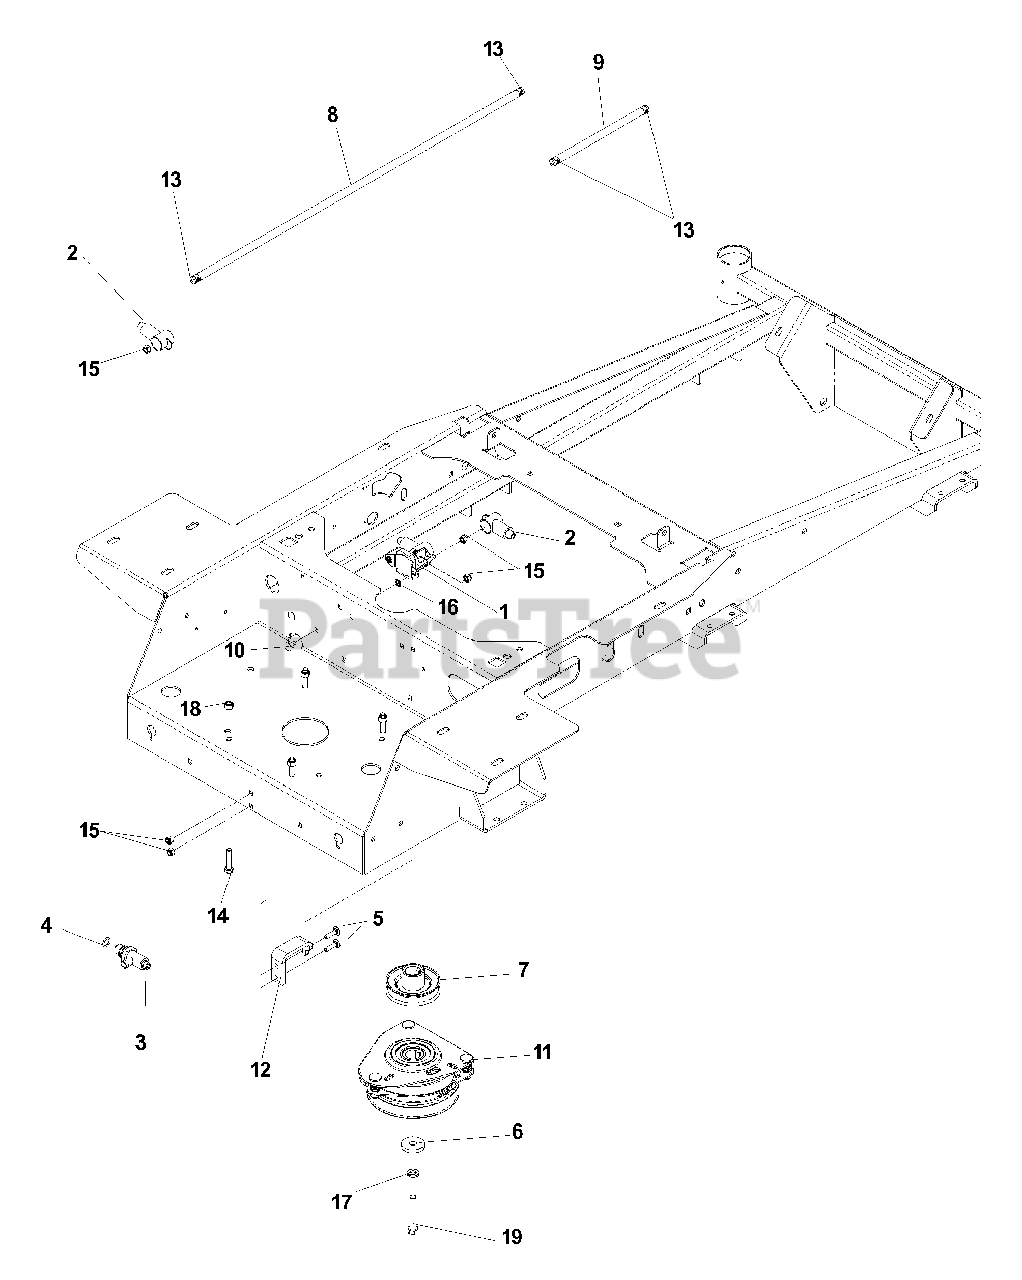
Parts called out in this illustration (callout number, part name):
2	INSULATOR, BATTERY
3	OIL DRAIN EXTENSION
5	RHSNB, 1/4-20 X 1, GR5
6	CLUTCH WASHER
8	FUEL LINE, 24"
9	FUEL LINE, 5"
10	RHSSNB, 1/4-20 X 5/8, GR5
12	CLUTCH TIE DOWN
13	CLAMP, HOSE
14	HCS, 5/16-18 X 1 1-2, GR5
15	NUT, 1/4-20, NYLOC
16	WASHER, 1/4
17	WASHER, 7/16
18	NUT, 5/16-18, NYLOC
19	HCS, 7/16-20 X 2 1/2, GR5
